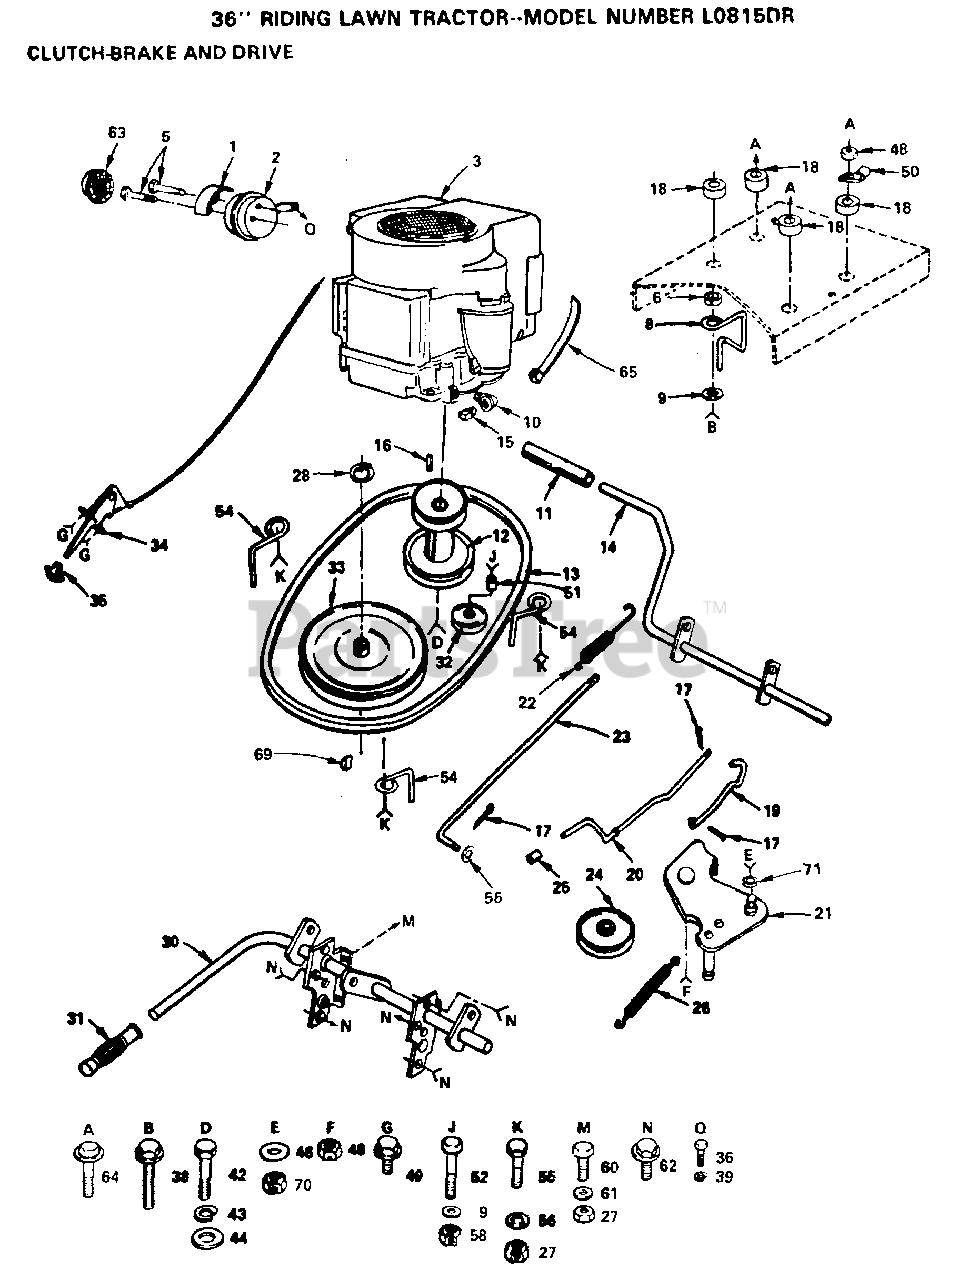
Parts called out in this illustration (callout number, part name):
1	SHIELD HEAT LTV
2	MUFFLER LTV
5	BOLT
6	SPACER LT
8	BELT SNUBBER T
9	WASHER
10	STREET ELBOW LT
11	PEDAL COVER T
13	V-BELT.83.0
14	FT PEDAL SHAFT LT
15	PLUG OIL DRAIN
16	SQ KEY STD
19	CLUTCH ROD LT
20	BRAKE ROD LT
21	IDLER BRKT T
22	BRAKE SPRING T
30	SHAFT ASSY LT
31	HANDLE GRIP
32	IDLER.PULLEY.LT
33	PULLEY.TRANSAXLE
36	BOLT
38	SCREW
39	LOCKWASHER
42	BOLT
43	LOCKWASHER
44	WASHER LT
46	WASHER
49	SCREW
50	CLIP T
51	SPACER T
52	BOLT
54	BELT SNUBBER T
56	WASHER M
58	LOCKNUT
60	BOLT
61	WASHER
62	SCREW LT
63	SCREEN
64	SCREW LT
65	WIRE TIE
71	SPACER T
